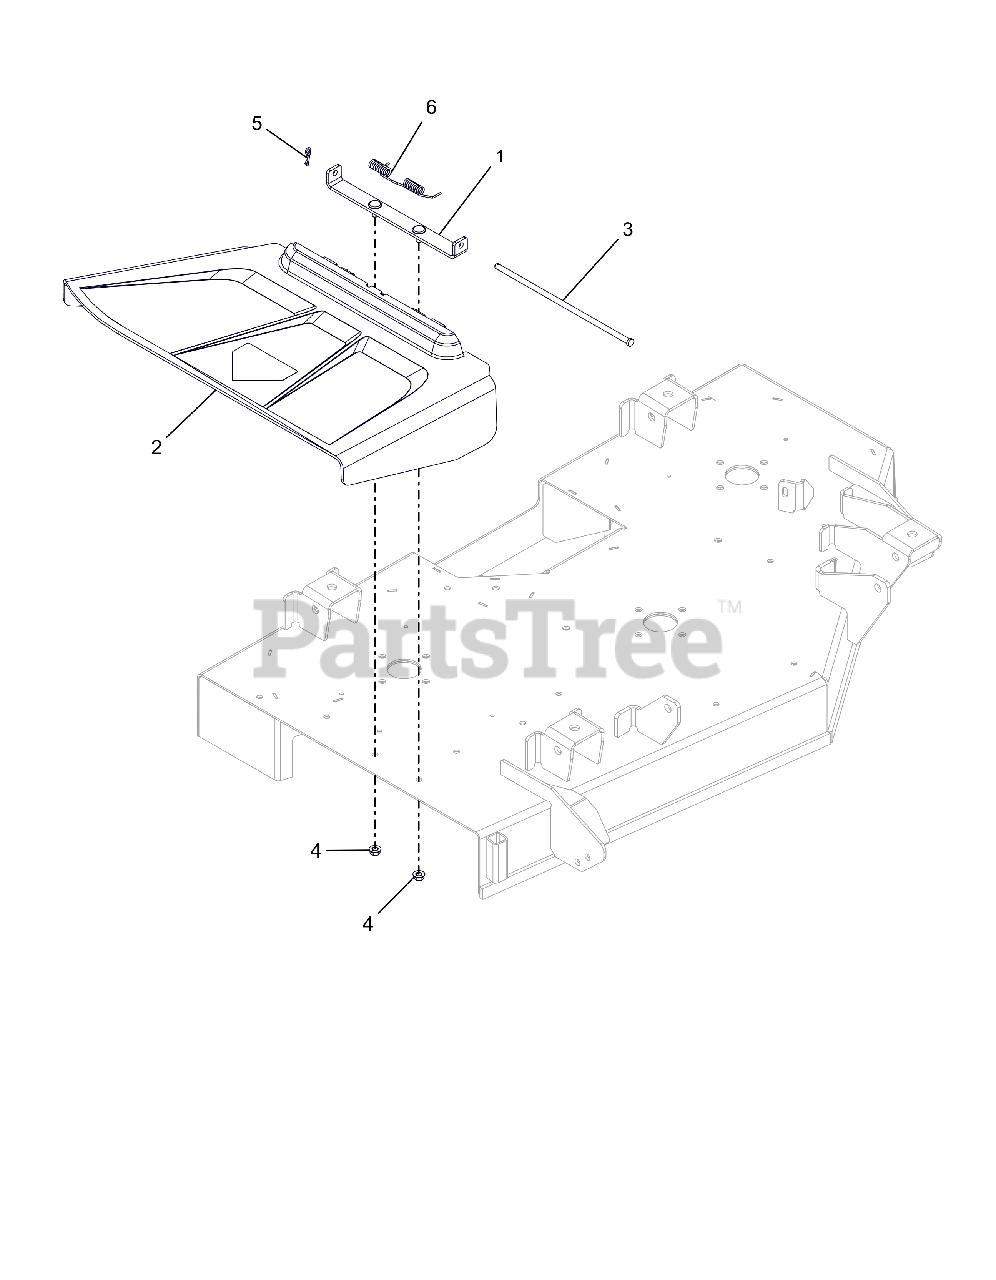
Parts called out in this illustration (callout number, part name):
1	WLDMT, CHUTE MT BRKT
2	CHUTE, SIDE DISCHARGE
3	PIN, 5/16 X 10.5
4	@NUT-LK-TOP-FLG .31-18 YWZC
5	PIN-HAIR INT .08X.18X1.18 YWZC
6	SPRING-TORSION
